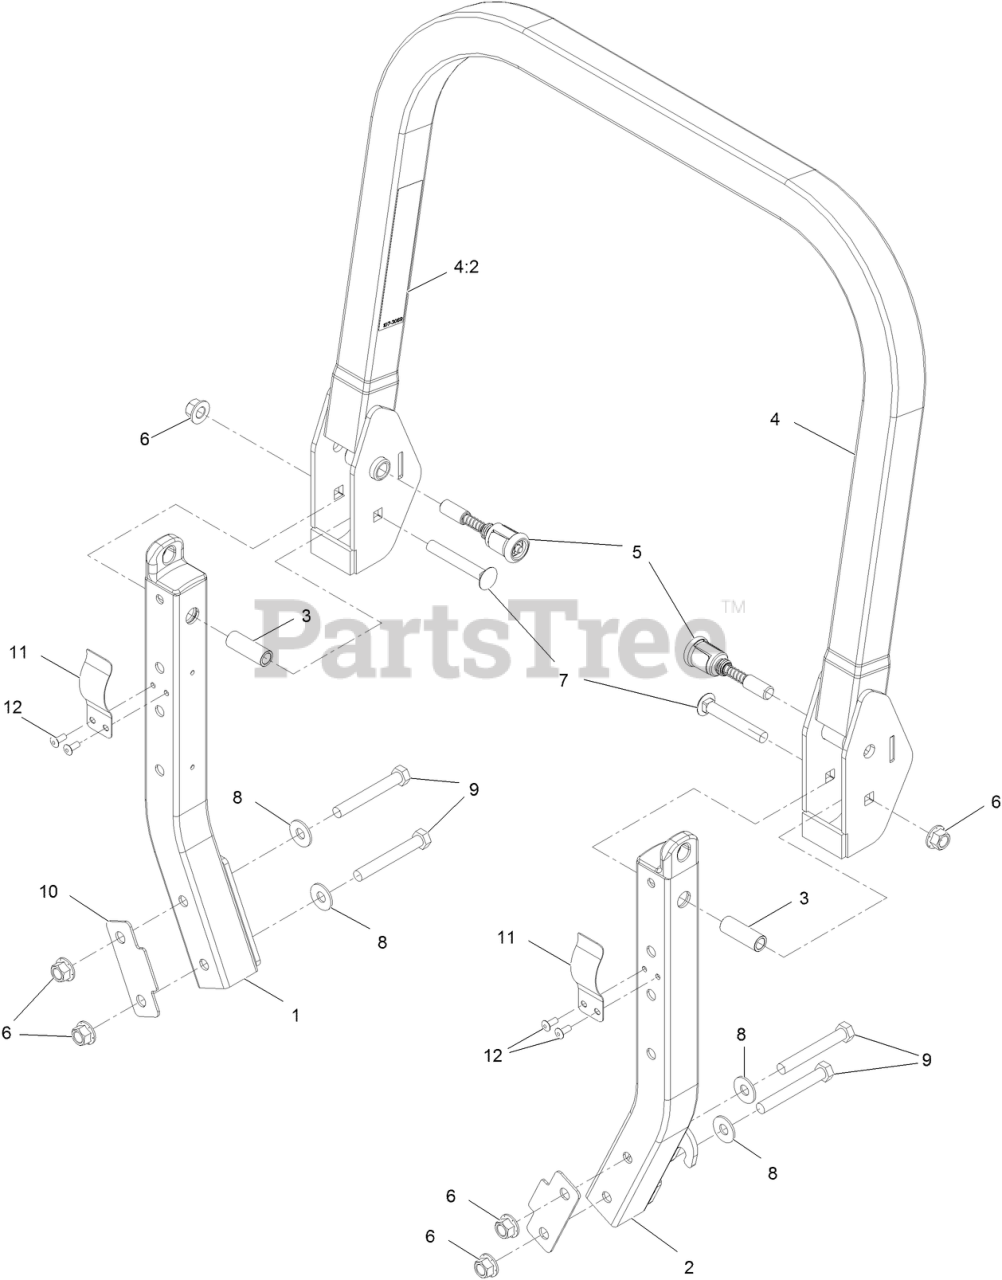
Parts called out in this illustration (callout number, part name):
1	LOWER-ROPS, RH
2	LOWER-ROPS, LH
3	SPACER
4	ROPS UPPER ASM
4:2	DECAL-WARNING
5	PIN-SPRING
6	NUT-LOCK
7	SCREW-CARR
8	WASHER-SPRING
9	SCREW-HH
10	SPACER
11	SPRING-LEAF
12	RIVET-BLIND
